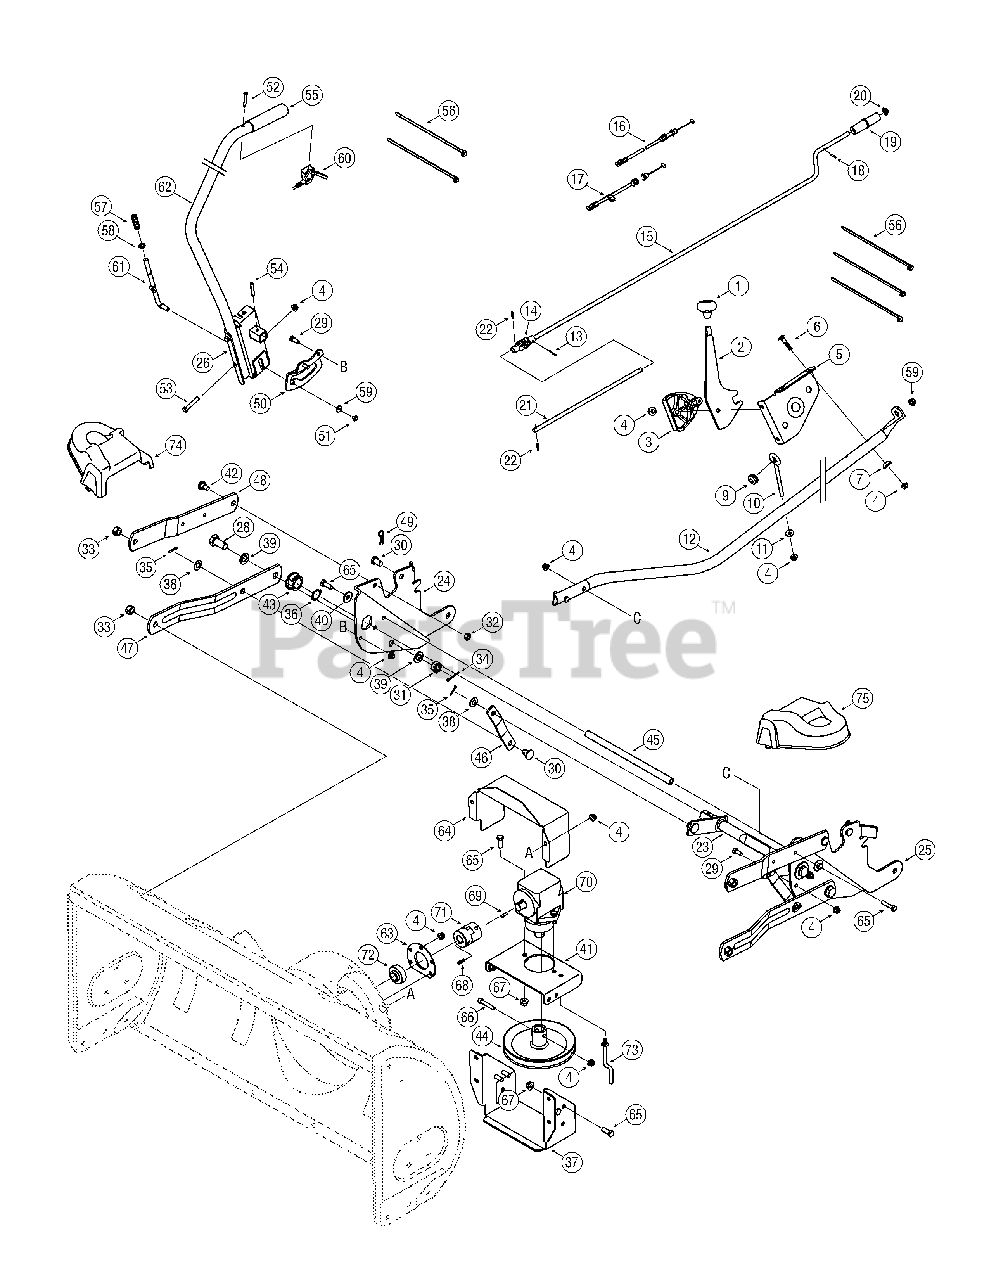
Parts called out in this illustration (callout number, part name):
2	Chute Tilt Handle
3	Chute Tilt Cable Guide
4	Nylon Hex Lock Nut, 5/16-18
5	Chute Tilt Bracket Assembly
6	Carriage Bolt, 5/16-18 x 1.5
7	Saddle Washer, .32 x .93
9	Rubber Grommet , .44 x .94 x .5
10	Eye Bolt
11	Bell Washer, .340 x .872
12	Support Chute Tube
13	Cotter Pin, 3/32 x .75
14	Joint Block Assembly
15	Chute Crank Rod, .375 x 33
16	Chute Cable, 62"
17	Chute Cable w/ Clip, 62"
18	Rolled Pin, 1/8 x .63
19	Crank Knob
20	Push Cap, 3/8 ID
21	Rod, .375 x 11.375
22	Spirol Pin, .125 x .82
23	Rod Assembly
24	RH Support Plate Assembly
25	LH Support Plate Assembly
26	Lift Bracket Assembly
28	Hex Cap Screw, 5/8-18 x 1.31
29	Hex Cap Screw, 5/16-18 x .75
30	Clevis Pin, .5 x .78
31	Slotted Hex Nut, 5/8-18
32	Hex Lock Nut, 3/8-16
33	Hex Lock Nut, 1/2-13
34	Cotter Pin, 1/8 x 1.25
35	Cotter Pin, .125 x .75
36	Snap Ring
37	Skid Plate
38	Flat Washer, .51 x 1.0 x .060
39	Flat Washer, .64 x 1.12 x .125
40	Bell Washer, .396 x 1.14 x .095
41	Drive Mounting Bracket
42	Shoulder Screw, .5 x .29, 3/8-16
43	Flange Bearing w/ Flats
44	Drive Pulley, 7"
45	Rod, 1/2 x 11.55
47	Link, 15.4
48	Link, 13.35
49	Click Pin
50	Snow Thrower Lift Bracket
51	Hex Index Washer Screw #10-16
52	Pan Phillips Screw, #10-24 x .75
53	Hex Cap Screw, 5/16-18 x 1.75
54	Heavy Duty Spirol Pin, 1/4 x 1.5
55	Handle Grip
56	Cable Tie
57	Compression Spring
58	Flat Washer, .385 x .62 x .063
59	Flat Washer, .194 x .62 x .063
60	Lift Cable, 42" w/ Trigger Control
61	Lift Index Rod
62	Lift Handle Tube
63	Bearing Housing, 1.85 ID
64	Belt Cover
65	Hex Cap Screw, 3/8-16 x 1.0
66	Socket Head Cap Screw
67	Flange Lock Nut, 3/8-16
68	Square Key, 3/16 x .75
69	Hi-pro Key, 3/16 x .75
70	Right Angle Drive
71	Coupling
72	Flange Ball Bearing, .75 x 1.85
73	Belt Keeper Rod
74	Steering Linkage Cover RH
75	Steering Linkage Cover LH
